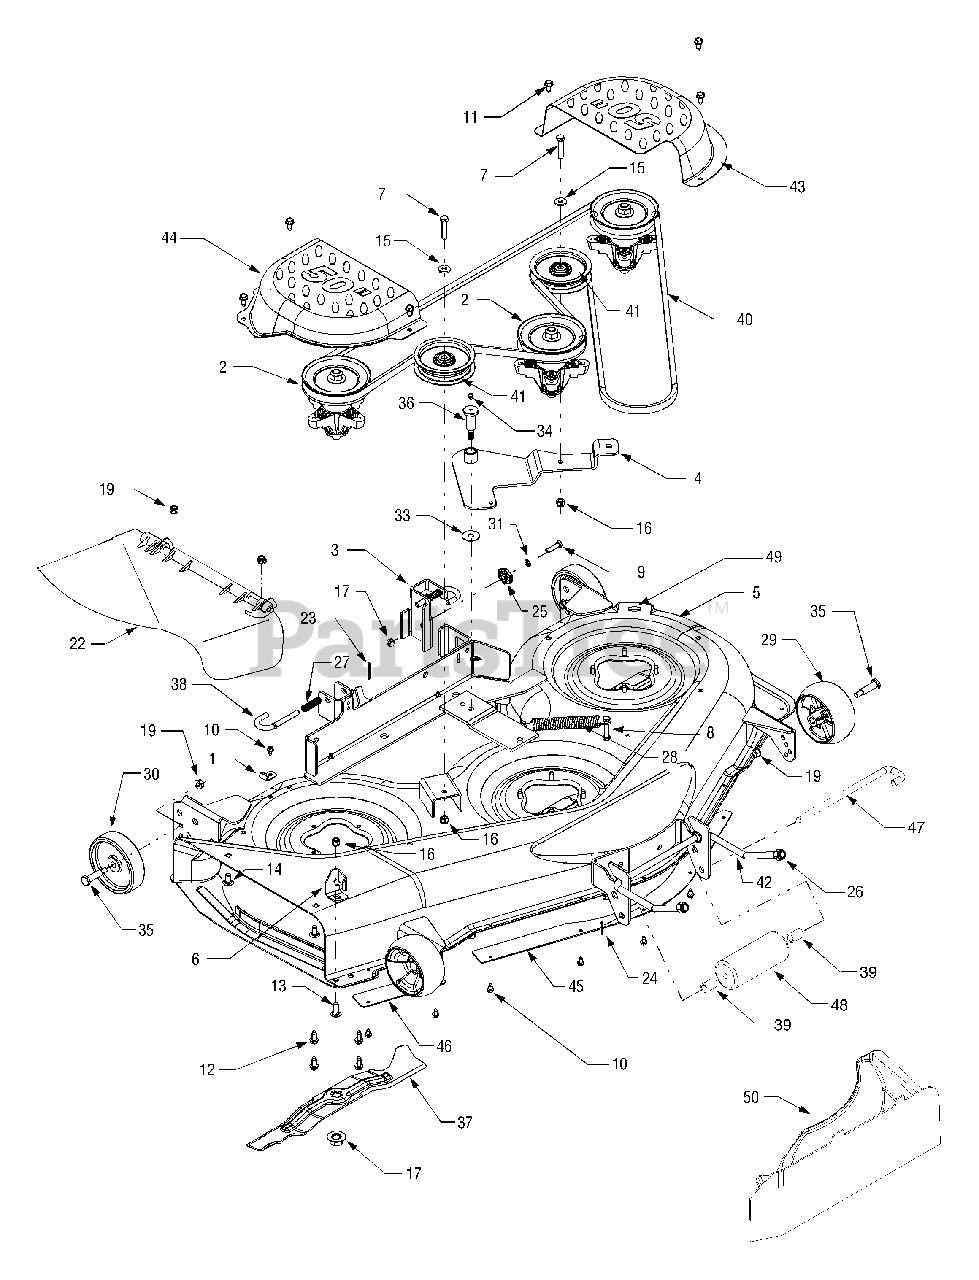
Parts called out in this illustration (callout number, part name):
1	Hook, Retainer
2	Spindle Assembly
7	Screw, 3/8-16, 1.75
8	Screw, 5/16-18 x 2.00
9	Screw, 5/16-18, 1.25, Gr5
10	Screw, 1/4-20 x 0.5
11	Screw, 5/16-18 x.625
12	Screw, 5/16-18 x.75
13	Screw, Carriage, 3/8-16 x 1.0
14	Screw, Carriage, 3/8-16 x.75
15	Washer, Flat,.406 x.875 x.059
16	Nut, Nylon Lock, 3/8-16
17	Nut, Hex, Flange, 5/8-18
18	Nut, Nylon Lock, 5/16-18
19	Nut, Flange Lock, 3/8-16
20	Nut, Hex, 5/16-18, Gr5
21	Nut, 7/16-14
22	Chute Assembly, Side Discharge
23	Pin, Cotter, 1/8 x 1.25
24	Pin, Cotter, 3/32 x 1.25
25	Deck Adjustment Gear
26	Lock Nut, Hex, 1/2-13, Nylon
27	Spring, Compression,.531 x 1.75
28	Spring, Extension,.94 x 6.74
29	Deck Wheel, 5.0
30	Deck Wheel, 5.0
31	Washer, Lock, 5/16, Regular Duty
32	Washer, Bell,.45 x 1.0 x.062
33	Washer, Flat,.442 x 1.38 x.060
34	Fitting, Lube, 3/16
35	Shoulder Screw
36	Screw, Shoulder,.68 x 1.59
37	Blade
38	Rod, Handle, Deck Release.375 Via
39	Spacer,.550 x.755 x 1.1
40	Belt, V-Type, Aramid
41	Pulley, Idler, 3.5"
42	Rod, Deck Adjustment
47	Roller Pin, 5"
48	Front Roller
49	Screw Plug
50	Mulching Plug
